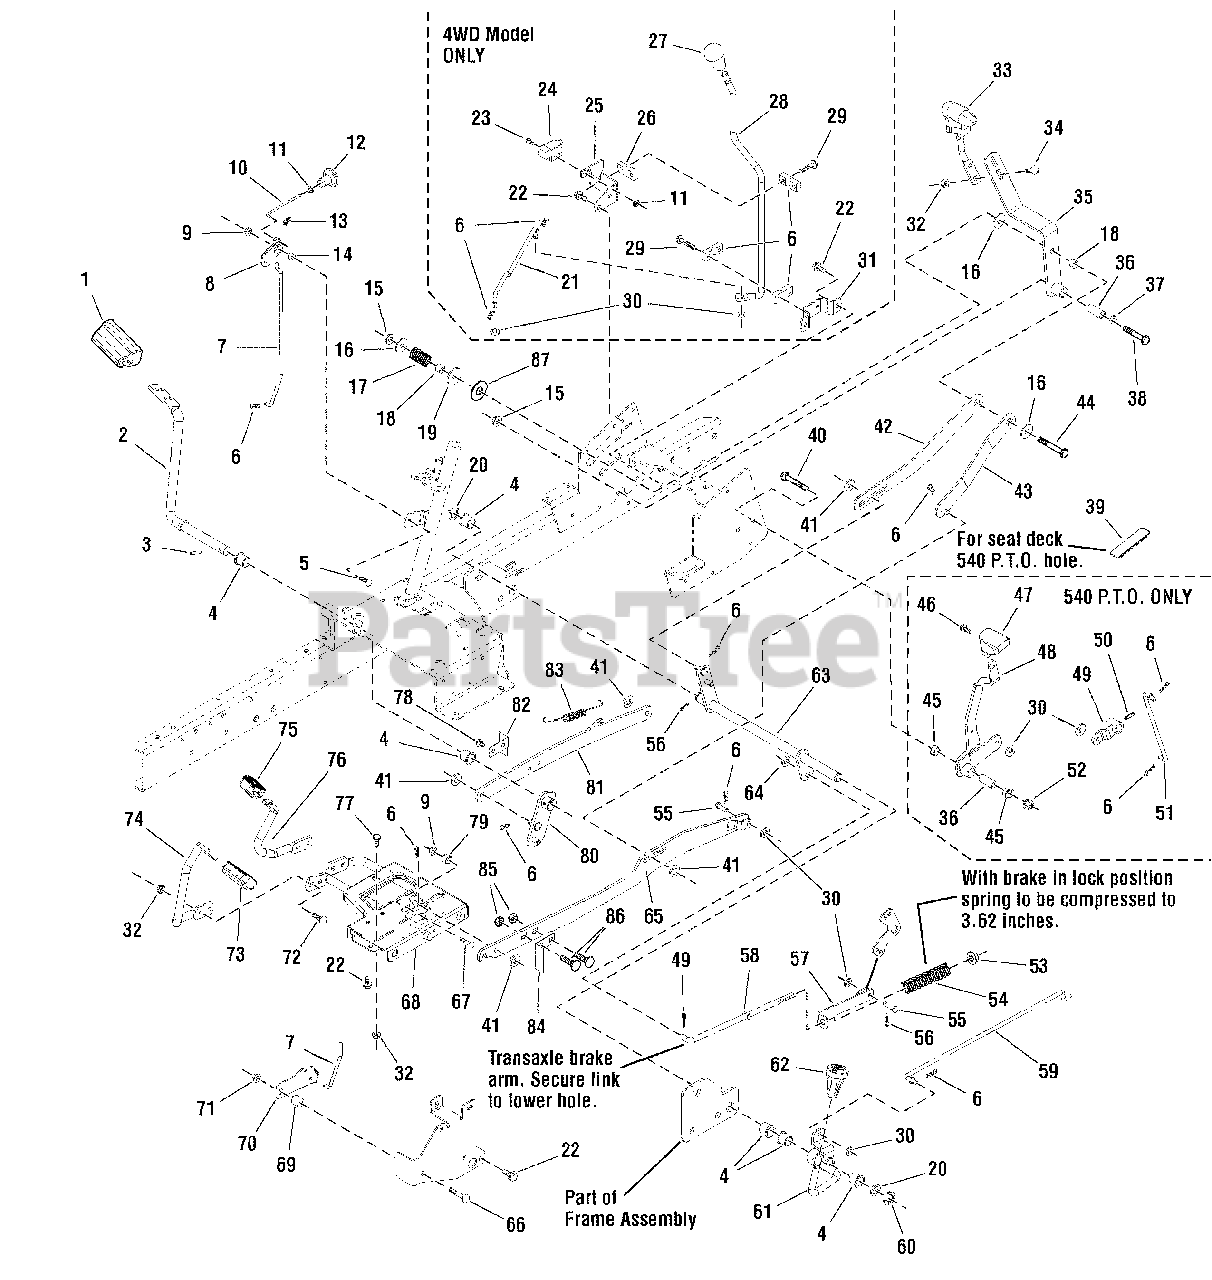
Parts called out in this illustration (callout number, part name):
1	PAD, Brake Pedal
2	ROD, Brake Pedal
3	PIN, Spring
5	CARRIAGE BOLT, 1/4-20 x 3/4 G5
6	PIN, Quick
7	ROD, 4 Bends, 13.63 LG
8	BRACKET, Parking Brake Pivot
9	NUT, Hex, KEPS, 1/4-20 Conical Washer
10	ROD, 10-24 x 31/50, 3.91 LG
11	NUT, Hex, KEPS, #10-24
12	KNOB, Interior Thread, Parking
13	CLIP, Rod End Linkage, L.H., For .188 Rod
14	SPACER, .320 LG
15	NUT, Hex, Flange, 3/8-16, ESNA
16	WASHER, 3/4
17	SPRING, Complete
18	SPACER, 7/16 LG Powdered Metal
19	WASHER, 3/8
20	WASHER, 3/4
21	ROD, 4WD Shift, 10.74 LG
22	SCREW, Hex Washer Head, Taptite, 5/16-18 x 3/4
23	SCREW, Hex Washer Head, Slot #10-24 x 5/8
24	SWITCH, Push Button, Nuetral/Start
25	BRACKET, 2 Speed Pivot
26	BEARING HALF, Outer Nylon
27	KNOB, Sphere Softer
28	ROD, Shift 2 Speed, 19-1/4 LG
29	SCREW, Hex Washer Head, Taptite, 5/16-18 x 1-1/2
30	WASHER, 5/16
31	BRACKET, Mounting, 4.63 LG
32	NUT, Hex, KEPS 5/16-18, Conical Washer
33	KNOB, With Cruise Control Rod Molded In
34	BOLT, Carriage, Short Neck, 5/16-18 x 1
35	LEVER ASSEMBLY, Cruise
36	SPACER, 1-1/2 LG HARDEN
37	WASHER, 3/8
38	CAPSCREW, Hex Head, 3/8-16 x 2-1/4 G5
39	COVER, Black Rubber, .98 x 3.88
40	BOLT, Carriage, 3/8-16 X 2 1/2
41	WASHER, 3/4
42	ARM, Cruise Return
43	LINK & PIN ASSEMBLY, Cruise
44	CAPSCREW, Hex Head, 3/8-16 x 3.00
45	BUSHING, 2/5 LG Powdered Metal
46	SCREW, 1/4-20 x 7/8
47	HANDLE, 540 PTO 3/8 x 7/8 Slot
48	HANDLE ASSEMBLY, Control
49	ARM & HUB ASSEMBLY, Control
50	PIN, Spring
51	ROD, Control, 9.23 LG
52	NUT, Hex, KEPS, Conical Washer, 3/8-16
53	NUT, Hex, Toplock Flange 7/16-20
54	SPRING, Complete
55	PIN, Clevis
56	PIN, Cotter 3/32 X 3/4
57	LINK & BRACE ASSEMBLY, Brake
59	ROD, Diff Lock, 20.7 LG
60	RING, Klipring Extension, 3/4 Shaft
61	PEDAL ASSEMBLY, Diff Lock
62	KNOB, Hole, 1/2 x 1-3/4, 2-11/16
63	SHAFT ASSEMBLY, Brake
64	WASHER, 7/16
65	ARM ASSEMBLY, Control
66	CARRIAGE BOLT, 5/16-18 x 1-1/2 G5
67	CARRIAGE BOLT, 1/4-20 x 1-1/4 G5
68	CONTROL ASSEMBLY, Foot Pedals
70	ARM, Brake Lock
71	NUT, Hex Flange, 5/16-18, ESNA
72	CARRIAGE BOLT, 5/16-18 x 7/8 G5
73	PAD, Foot Pedal, Forward
74	PEDAL, Foot, Forward
75	PAD, Foot Pedal, Reverse
76	PEDAL, Reverse
77	CAPSCREW, Hex Head, 5/16-18 x 3/4 G5
78	SCREW, Hex Washer Head, Taptite, 5/16-18 x 1/2
79	CAM, Roller
80	ARM ASSEMBLY, Brake
81	LINK, Brake
82	ACTUATOR, Switch 20GA
83	SPRING, Extension, 5/8 x 6-5/8
84	ACTUATOR, Switch 20GA
85	NUT, Hex Nylon, 1/4 -20
86	BOLT, Carriage, 1/4-20 x 5/8
87	DISC, Friction
